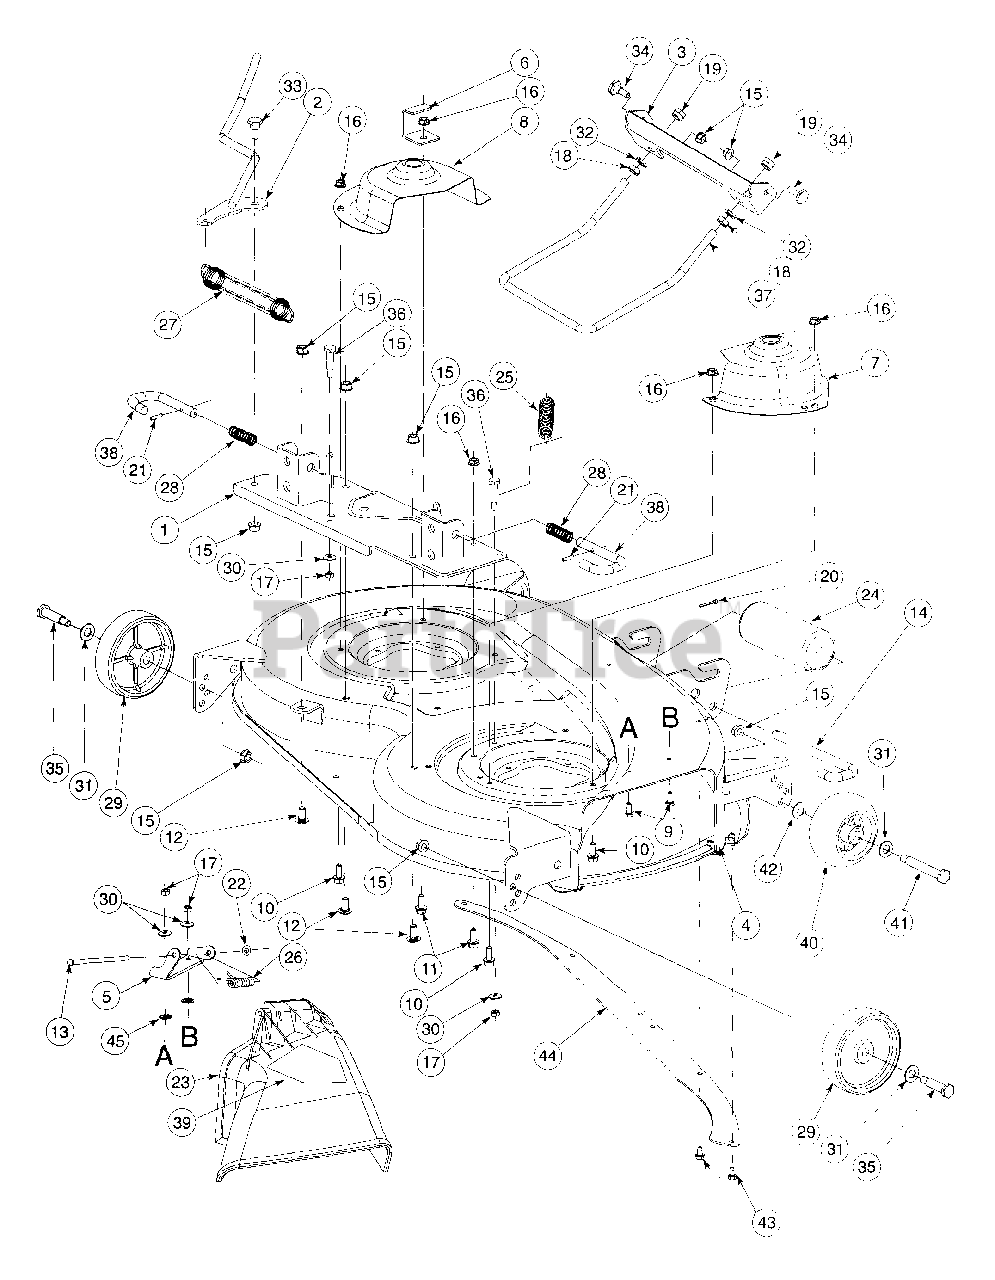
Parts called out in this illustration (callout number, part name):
5	Bracket, Hinge Mounting
9	Screw, Hex Cap, 1/4-20 x .62 GR5
10	Screw, Hx Wsh Hd Tapp, 5/16-18 x .75
11	Screw, Hex Cap, 5/16-18 x .75 GR5
12	Bolt, Carriage, 3/8-16 x .75
13	Pin, Hinge, .25 Dia x 6.75 Lg
14	Pin, Roller, 1/2 Dia x 7.31 Lg
15	Nut, Hex Flange Lock, 3/8-16
16	Nut, Hex Flange Lock, 5/16-18 GR5
17	Nut, Hex, 1/4-20
18	Nut, Hex Jam, 1/2-13 GR5
19	Nut, Hex Insert Lock, 1/2-13
20	Pin, Cotter, 3/32 x 1.25
21	Pin, Spirol Spring, 3/16 x .75
22	Cap, Speed Nut
23	Deflector Assy
25	Spring, Extension, .88 OD x 6.12
26	Spring, Torsion
27	Spring, Extension, 1.25 OD x 8.15
28	Spring, Compression
29	Wheel, Deck, 5 in. Dia
30	Washer, Bell, .265 x .75 x .062
31	Washer, Flat, .510 x 1.0 x .060
32	Washer, Lock, 1/2
33	Bolt, Shoulder, .498 Dia x .340 Lg
34	Bolt, Shoulder, .50 Dia x .434 Lg
35	Bolt, Shoulder, .498 Dia x 1.64 Lg
36	Bolt, Shoulder, .375 Dia x 1.16 Lg
37	Rod, Front Lift
38	Pin, Mower Support
39	Graphic, Danger
40	Wheel, Deck w/Fitting
41	Bolt, Shoulder, 1/2 x 2.5
42	Washer, Bell, .401 x .870 x .063
43	Screw, Self Tapping, 1/4-20 x .5
45	Nut, Push, 1/4
